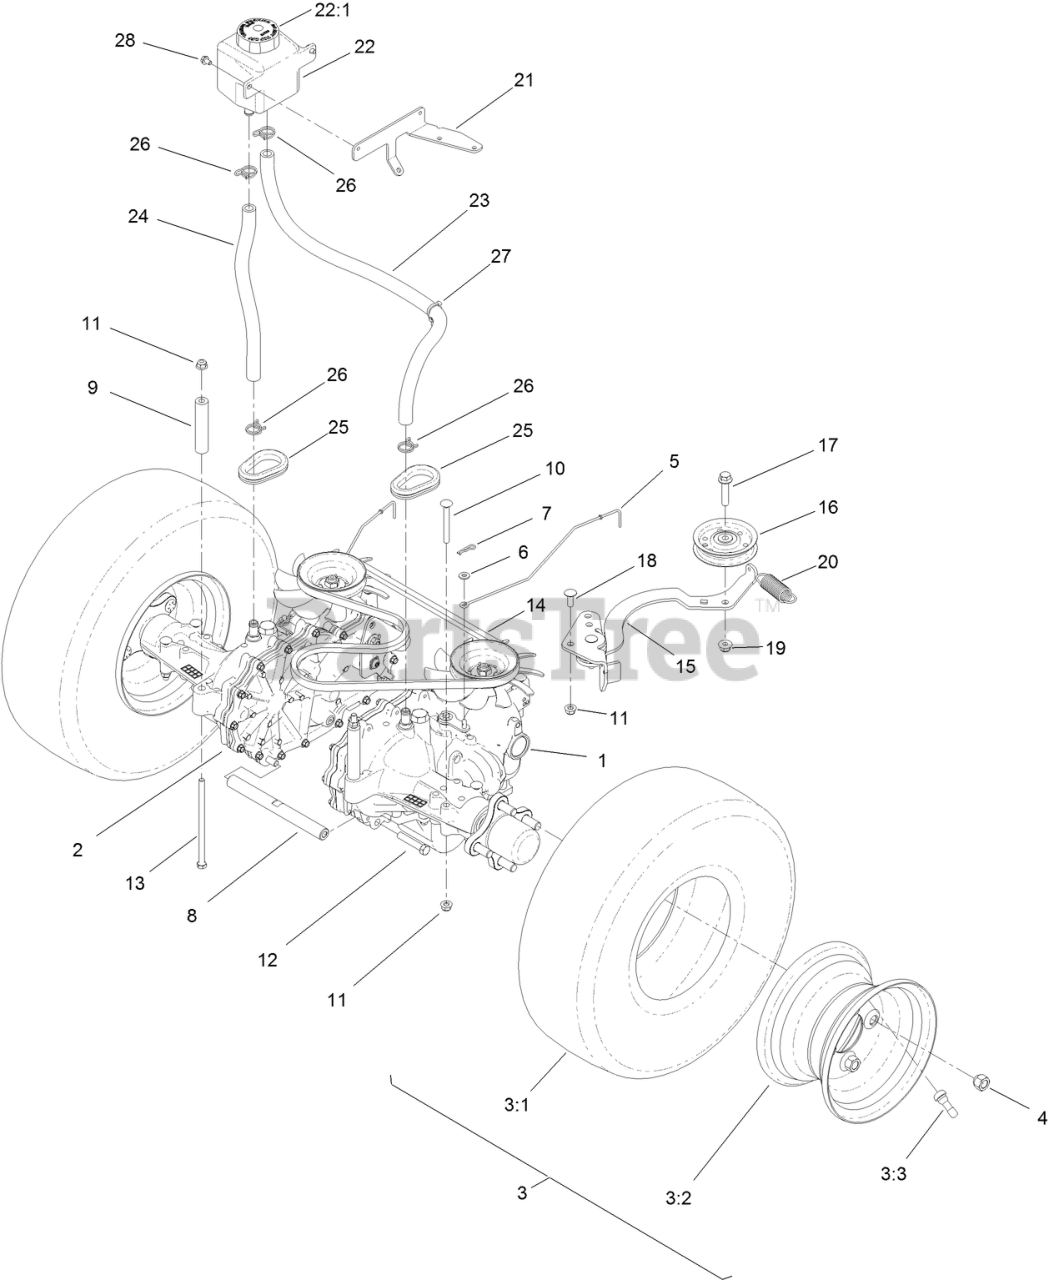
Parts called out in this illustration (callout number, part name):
1	TRANSMISSION, ZT-2800 LH
2	TRANSMISSION, ZT-2800 RH
3	WHEEL AND TIRE ASM
3:1	TIRE-4 PLY
3:2	RIM-8"
4	NUT-LUG
5	ROD-BYPASS
6	WASHER-FLAT
7	PIN-COTTER
8	SHAFT-CROSS, HYDRO
9	SPACER - TRANSMISSION
10	SCREW-CARR
11	NUT-HF, NI
12	SCREW-HH W/LOCTITE
13	SCREW-HH
14	BELT-V
15	IDLER ARM PIVOT ASM
16	PULLEY-IDLER, FLAT
17	SCREW-HHF
18	BOLT-CARR
19	NUT-HF, NI
20	SPRING-EXTENSION
21	BRACKET - EXPANSION TANK
22	TANK-HYD
22:1	CAP-RESERVOIR, HYD
23	HOSE-HYDRO
24	HOSE-OVERFLOW
25	GROMMET
26	CLAMP-HOSE
27	CLIP-TIE
28	SCREW-HWH
